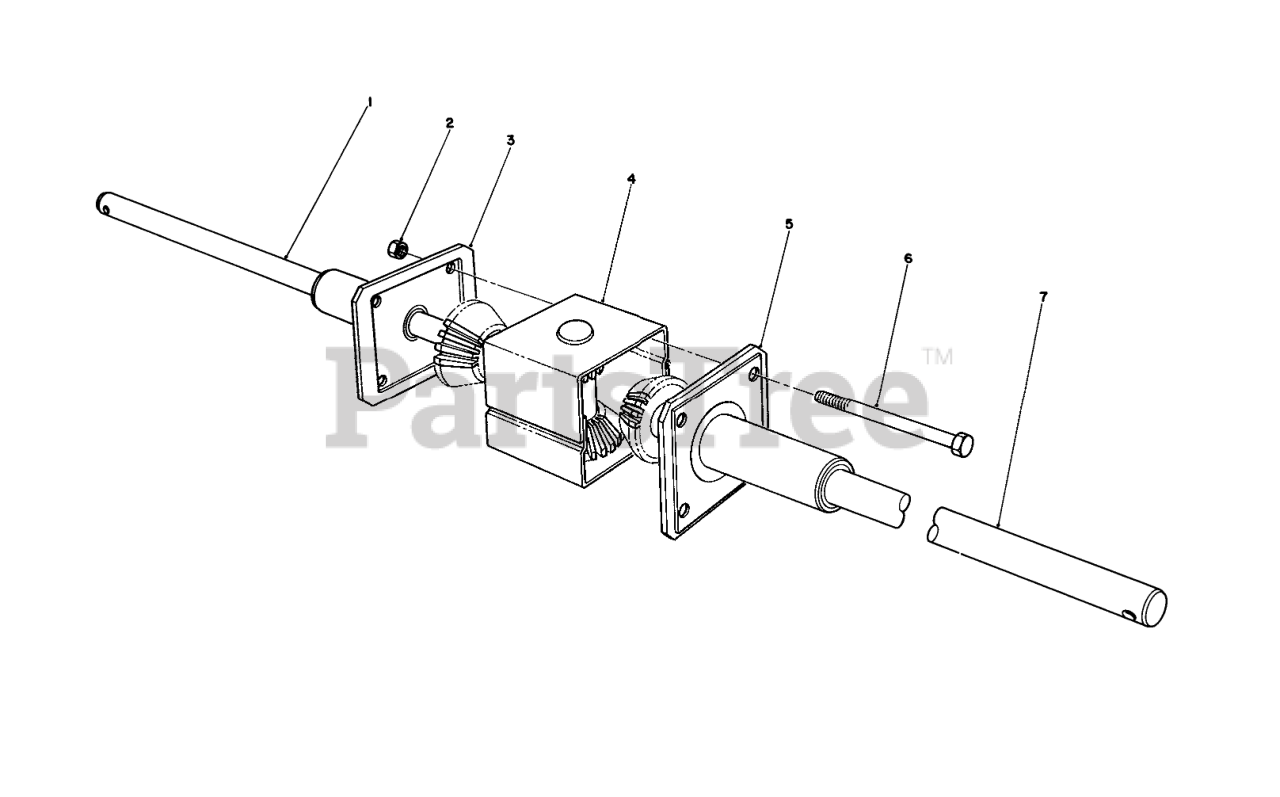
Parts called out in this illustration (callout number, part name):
2	NUT-LOCK, CONE
3	END CAP/BRG ASM
4	GEAR CASE ASM
5	END CAP &BEARING ASY
6	SCREW-HH
